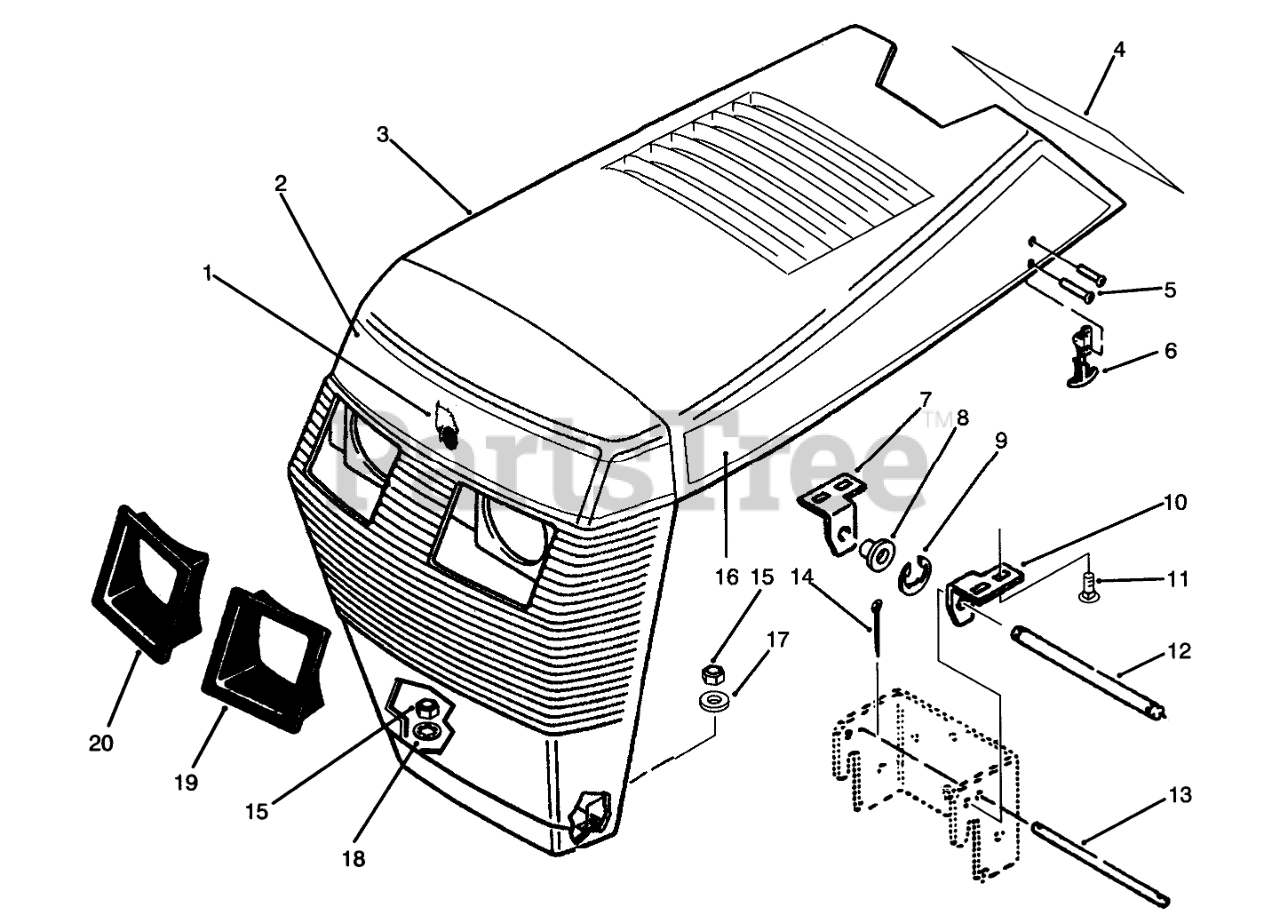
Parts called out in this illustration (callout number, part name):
1	PLATE - LOGO WHL HORSE
2	DECAL-FRONT HOOD, TOP
3	SERV.ASSY-HOOD & PKG
4	DECAL - DANGER
5	RIVET-POP
6	HANDLE ASM
7	BRACKET-GRILL, R H
8	BUSHING-NYLINER
9	RING-RETAINING
10	BRACKET-GRILL, LH
11	SCREW-CARR
12	ROD-GRILL PIVOT
13	ROD-HOOD STOP
14	PIN-COTTER
15	NUT-LOCK, NI
16	DECAL - LH HOOD TOP
17	WASHER-FLAT
18	WASHER-LOCK, INTERNAL
19	BEZEL-HEADLIGHT, LH
20	BEZEL-HEADLIGHT, RH
